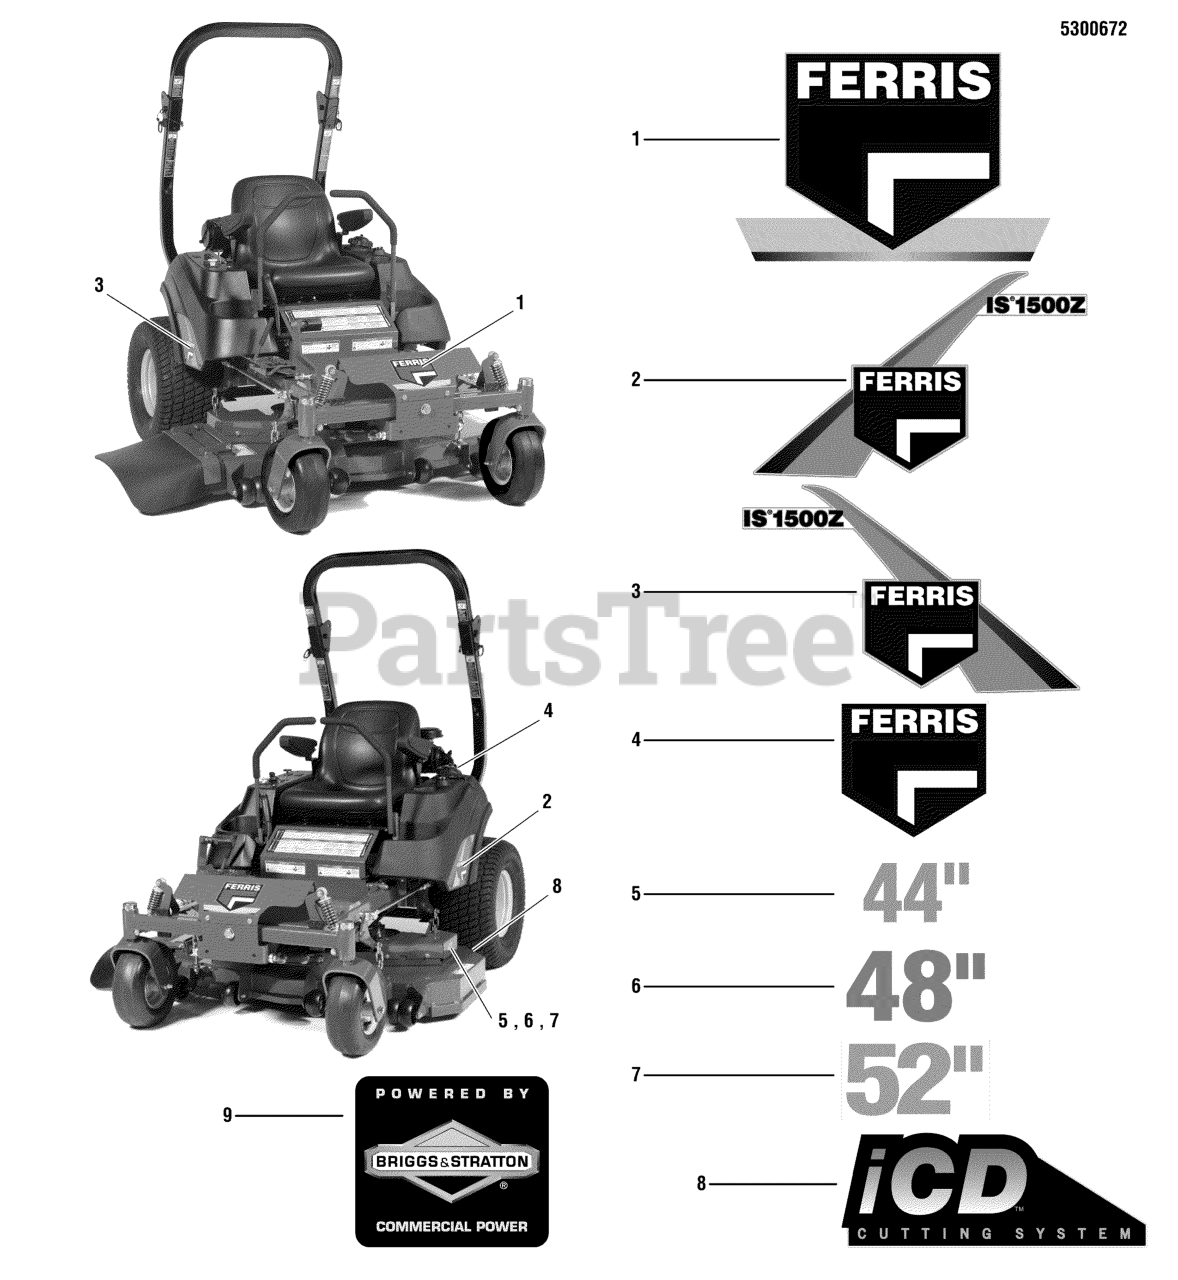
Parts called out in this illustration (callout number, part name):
1	DECAL, FERRIS, FRONT, 8.78 X 5.81
2	DECAL, BADGE - LH IS1500
3	DECAL, BADGE - RH IS1500
5	DECAL, 44
6	DECAL, 48
7	DECAL, 52
8	DECAL, iCD CUTTING SYSTEM
